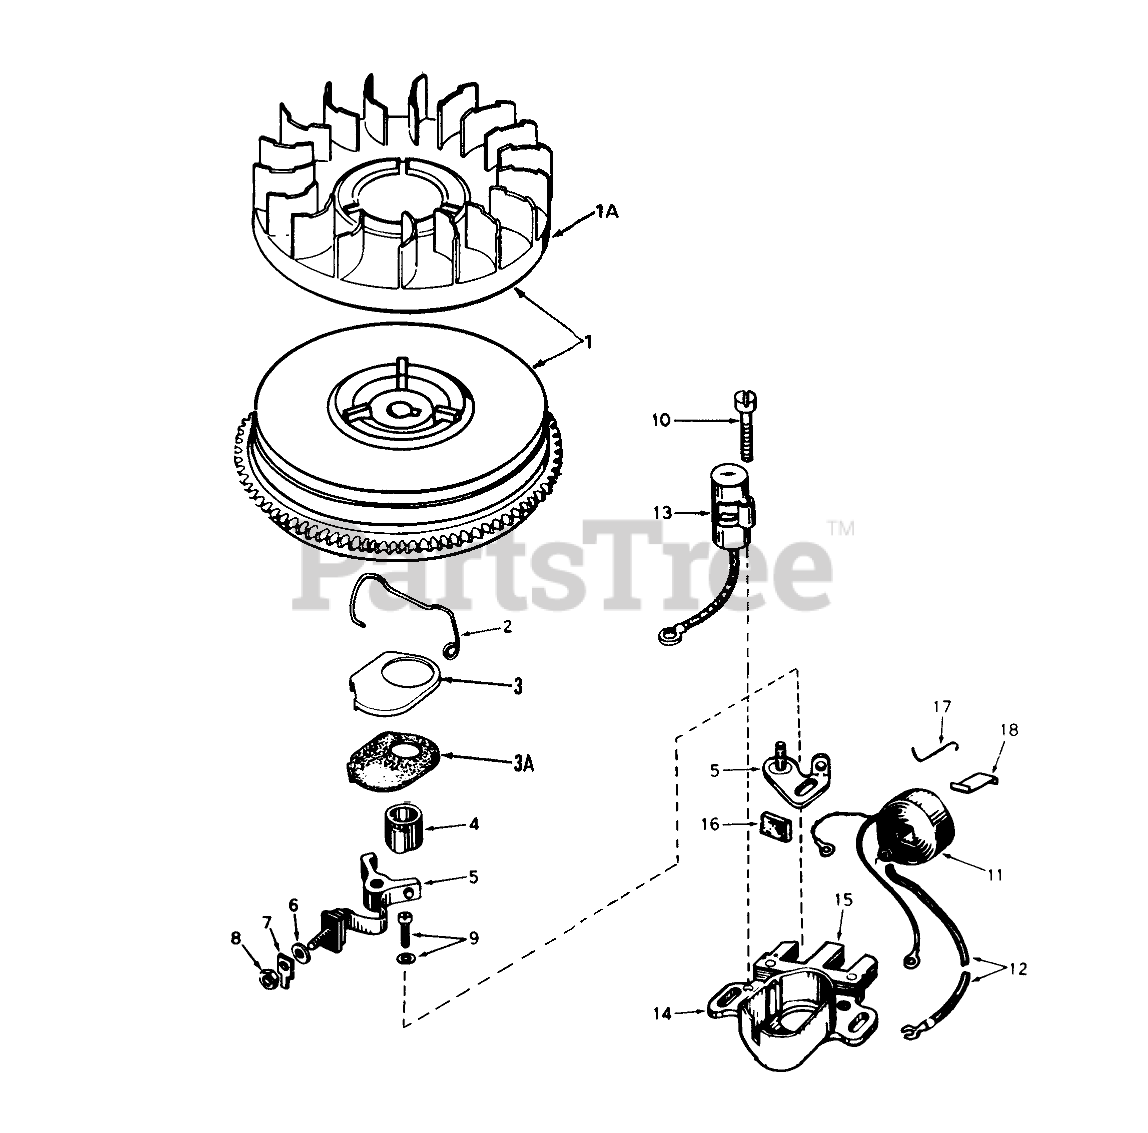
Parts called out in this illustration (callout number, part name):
1	Flywheel (Incl. #1A, 3 & 3A)
2	Spring Breaker Box
3	Cover-Dust
3A	Gasket, Dust Cover
4	Cam-Breaker
5	Breaker Assy.
7	Terminal, Ground
9	Breaker Screw
10	Condenser Screw
11	Coil Assy. (Incl. #12)
12	Wire, Lead
13	Condenser
14	Core & Plate
15	Stator Assy. (Incl. #2, 3, 3A, 5 thru 14 & 16 thru 18)
16	Felt,Cam Wiper
17	Clip, Coil
18	Spring Coil Wedge
